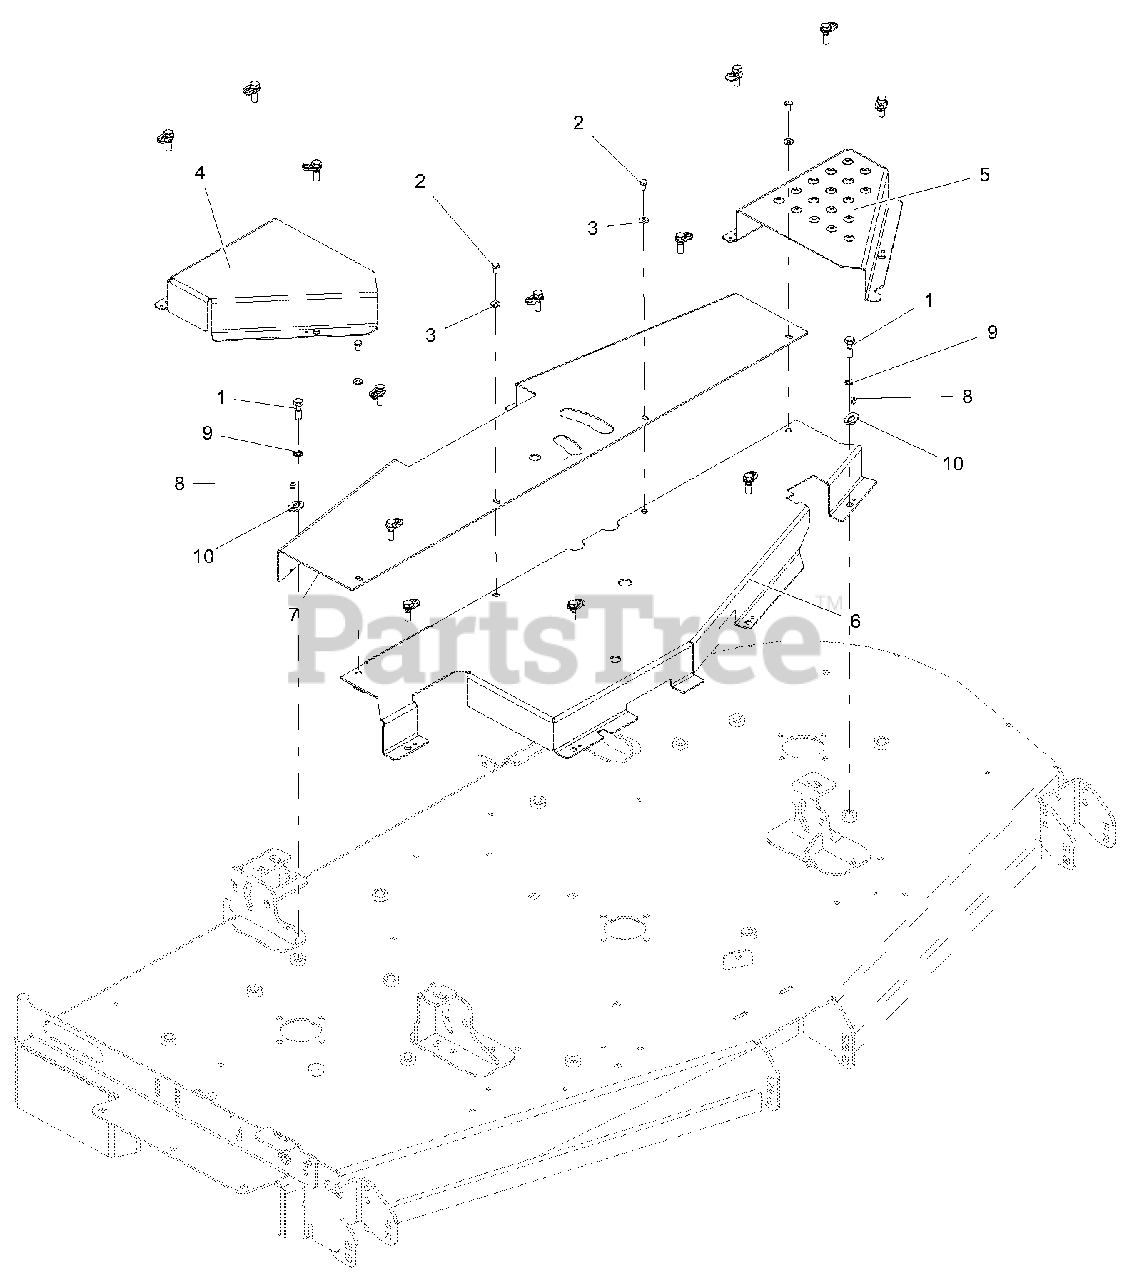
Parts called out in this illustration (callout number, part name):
1	BLT, HEX 0.38-16 X 1.25 GR5 CAPTIVE
2	BLT-HEX .25-20X.50 GR5 YWZC
3	WSHR-FL-STL.281X.62X.065 YWZC
4	GUARD, RH PT200 CE BELT (BLACK)
5	GUARD, LH PT200 CE BELT (BLACK)
6	BRKT, FRONT BELT GUARD 272-CE
7	BRKT, BACK BELT GUARD 272-CE (BLACK)
8	RVT-POP .187x.250 (#64) YWZC
9	LOCK, WSHR-EXT 0.391 X 0.628 X 0.036 YWZC
10	KEEPER, BOLT
